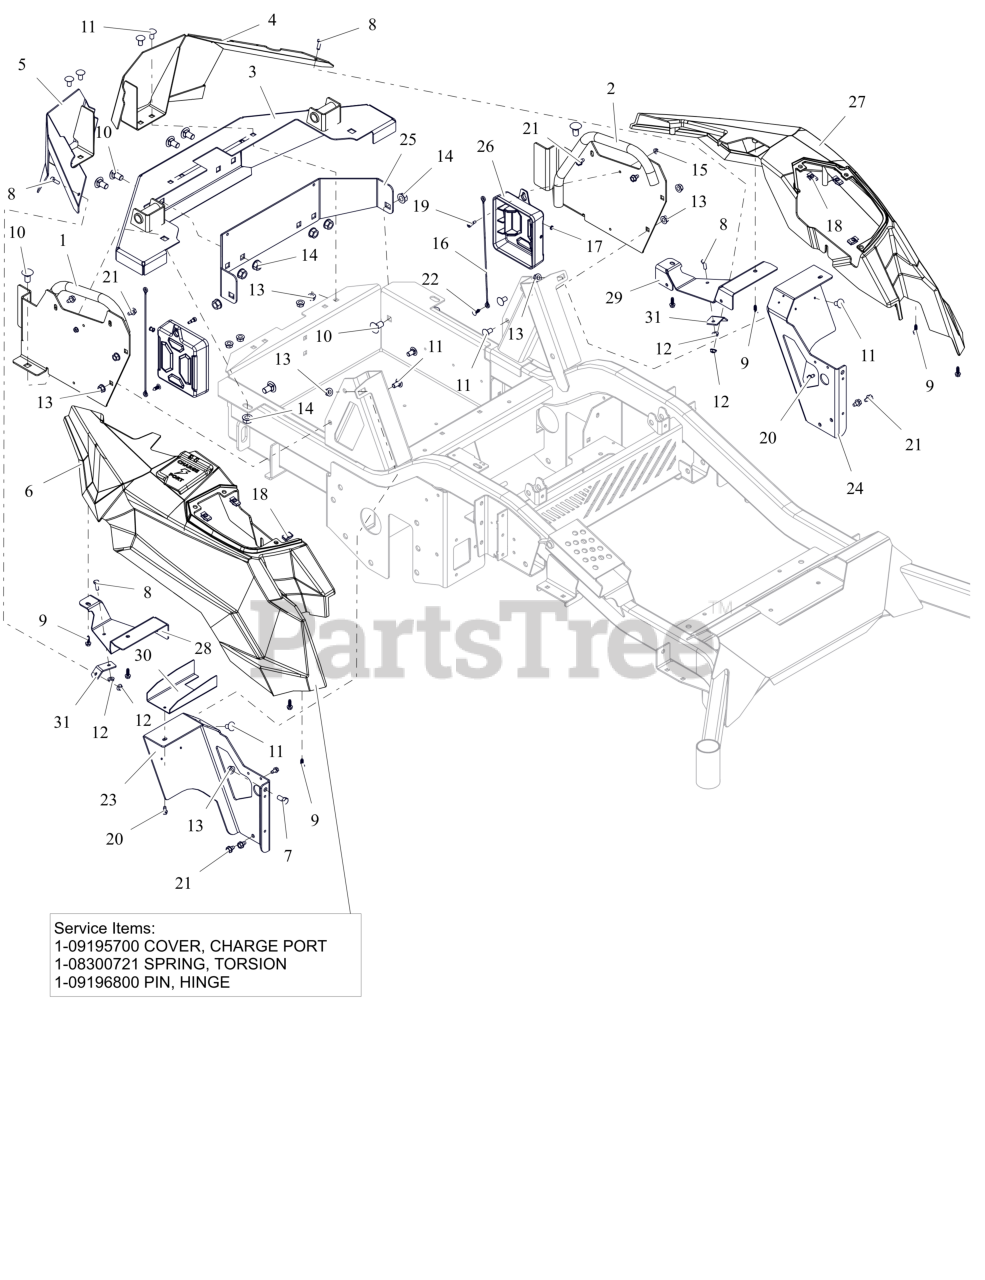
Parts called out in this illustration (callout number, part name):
1	WLDMT, REAR FENDER MOUNT-RH (ORANGE)
2	WLDMT, REAR FENDER MOUNT-LH (ORANGE)
3	WLDMT, BUMPER ZENITH E (ORANGE)
4	WLDMT, REAR WRAP-LH (BLACK)
5	WLDMT, REAR WRAP-RH (BLACK)
6	ASM, FENDER RH PRO-TURN EV
6	COVER, CHARGE PORT
6	SPRING, TORSION
6	PIN, HINGE
7	BLT,HEX .38-16X.75 G5 ZCC
8	BLT, HEX .25-20X.75 G5 ZCC
9	SCR, PLASTITE .25-10X.75 ZCC
10	BLT, RHSN .50-13X1.00 G5 ZCC
11	BTL,RHSSN .375-16 X 0.75 G5 FPB
12	NUT-LK-CTR-FLG .25-20 ZC120
13	NUT-LK-CTR-FLG .375-16 GF ZCC
14	NUT-LK-CTR-FLG .500-13 GG ZCC
15	NUT, FLG-TOP LK #10-24 GF ZCC
16	CABLE, 12.0 LANYARD, NYLON
17	POST, & SCREW, PUSH LOCK .25 X .25
18	NUT-RTNR .25-20X.56
19	BLT-SHLDR .25X.375
20	SCR-TAP .25-20X.50 HWH ZCC
21	SCR,TAP .312-18X.50 HWH TR ZCC
22	RIVET, .25 NYLON PANEL
23	MOUNT, FRONT FENDER-RH (ORANGE)
24	MOUNT, FRONT FENDER-LH (ORANGE)
25	SUPPORT, BUMPER (BLACK)
26	COVER, BATTERY BUSBAR TERMINAL
27	FENDER, LH PRO-TURN EV
28	SHIELD, FENDER MOUNT -RH (BLACK)
29	SHIELD, FENDER MOUNT-LH (BLACK)
30	SHIELD, DEBRIS -CHARGE PORT (BLACK)
31	STRAP, SUPPORT - REAR WRAP (BLACK)
